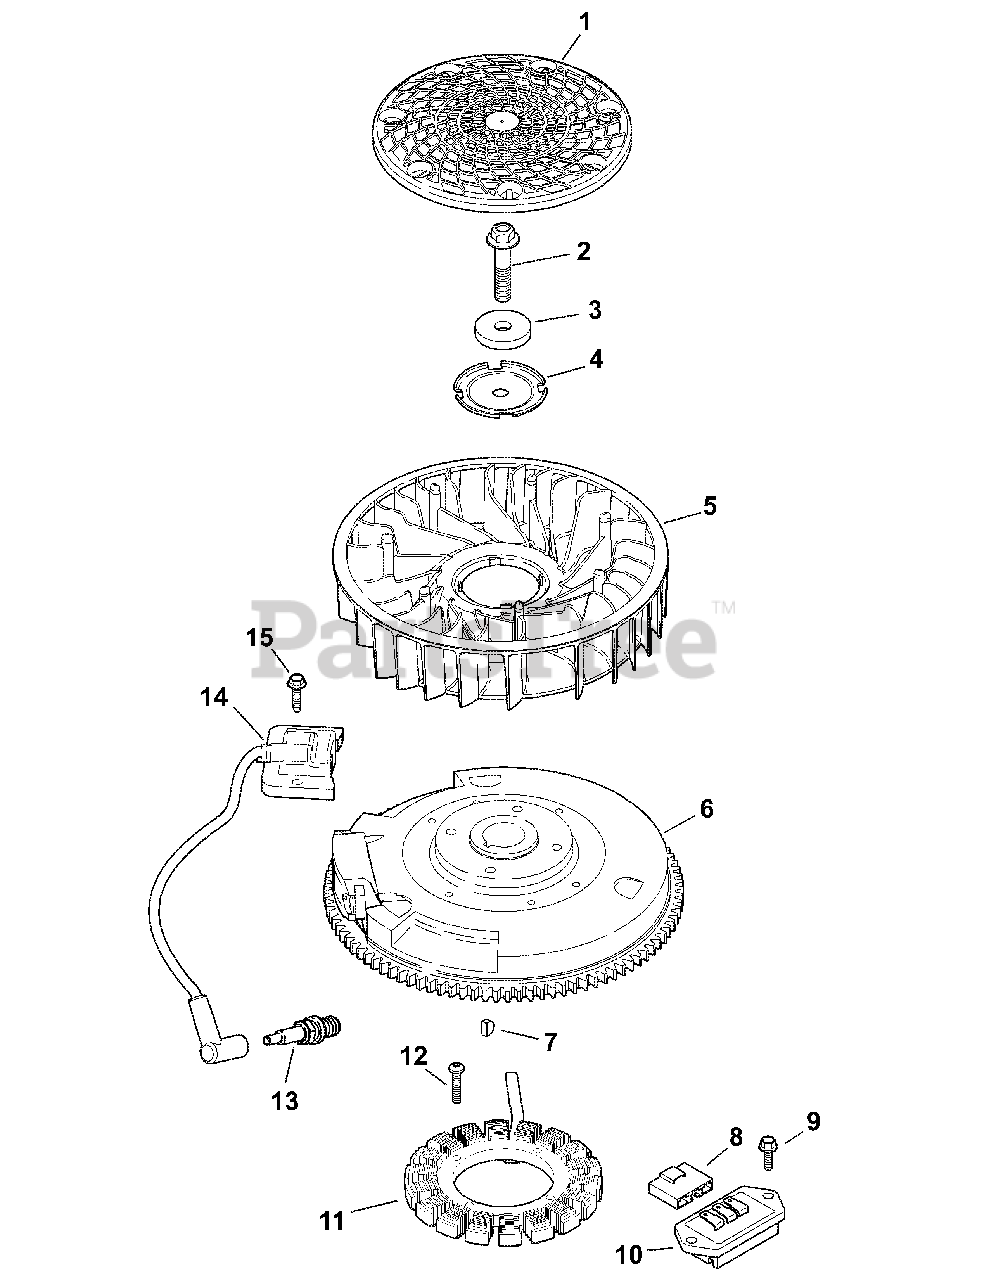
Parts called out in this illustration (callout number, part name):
1	Screen, Grass
2	Screw, FLG M10X1.5X45
3	Washer, Flat 13/32"
4	Plate, Fan Mounting
5	Fan
6	Flywheel
7	Key, 3/16" x 5/8"
8	Connector (3 Contact)
9	Screw, Hvy Flg M5 x 0.8 x 16
10	Rectifier-Regulator
11	Kit, 15 Amp Stator (Includes KH-25 452 01-S)
12	Screw, TRX HD Drive Fastener
14	Module, Ignition (CDI Fixed)
15	Screw, FLG THD FRM M5 x 0.8 x 20
